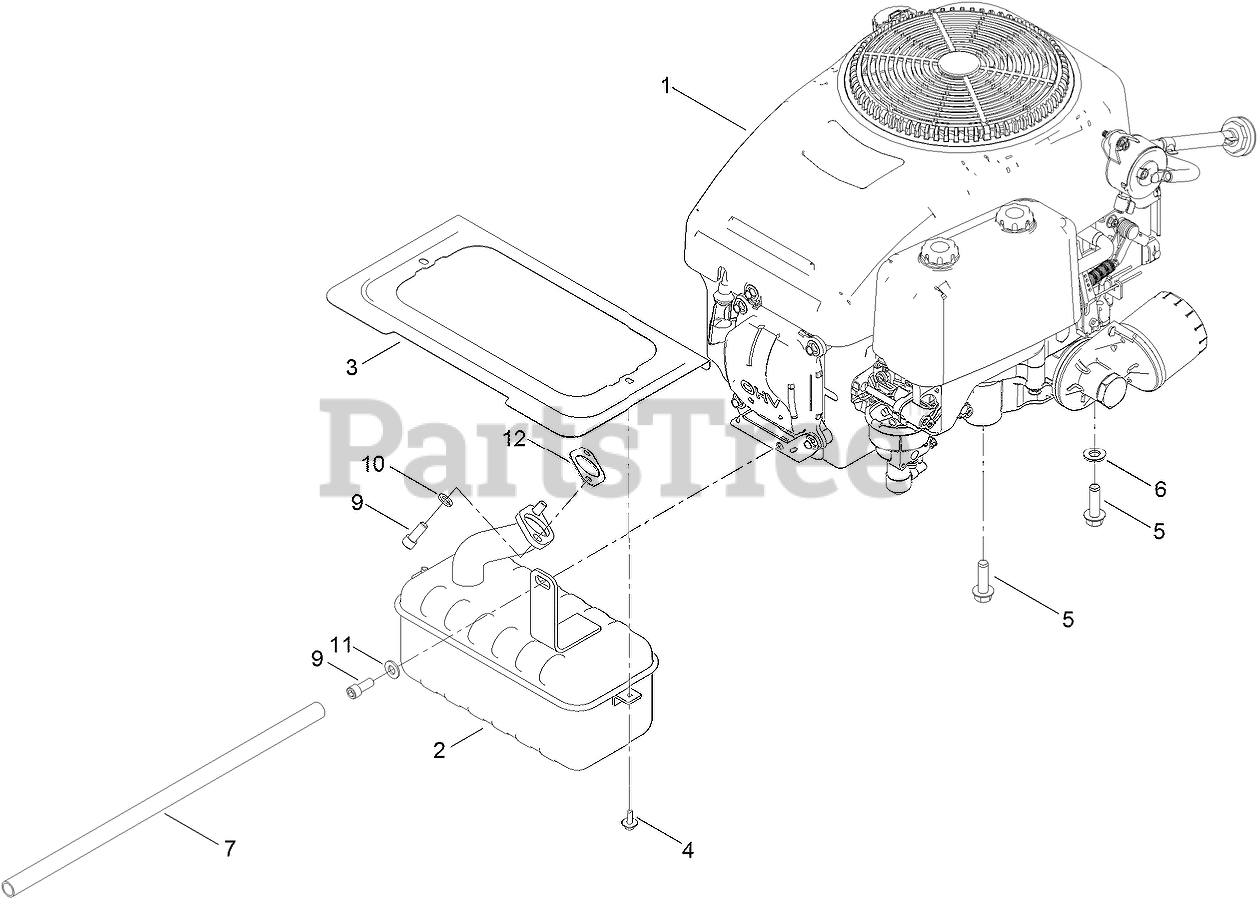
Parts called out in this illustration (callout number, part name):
1	ENGINE-1P92F-1
2	MUFFLER
3	SHIELD-HEAT
4	SCREW-HWH, THD ROLL
5	SCREW-HWH, THD ROLL
6	WASHER-FLAT
7	TUBE-DRAIN, OIL
9	SCREW-HSH
10	WASHER-LOCK
11	WASHER-PLAIN
12	GASKET-EXHAUST
